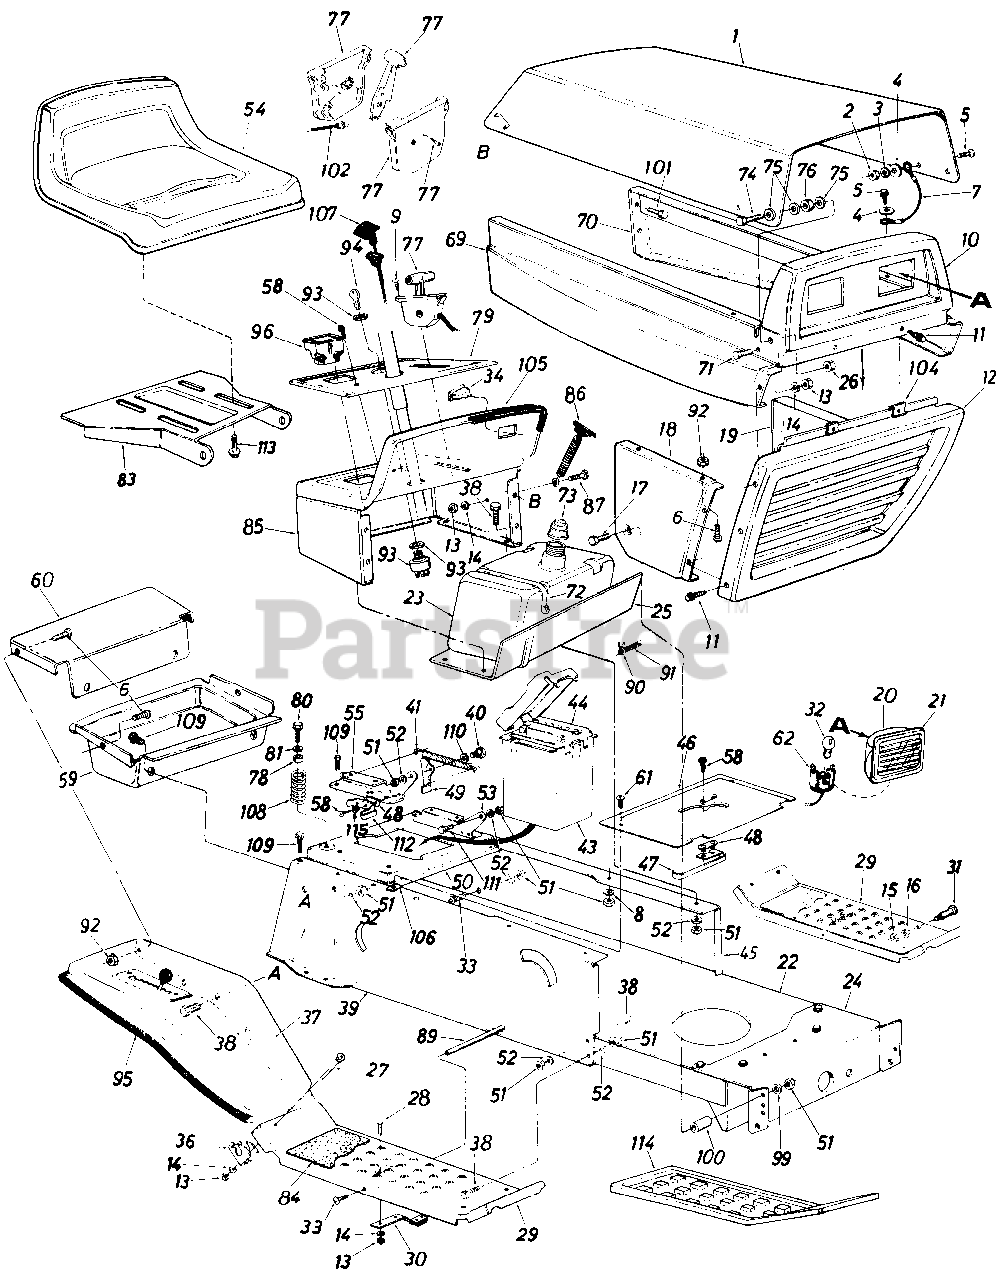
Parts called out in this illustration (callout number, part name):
3	L-Wash. #10 I.D.
4	Fl-Wash. .25" I.D. x .62"
5	Truss Scr. #10-24 x .375"
6	Truss Hd. Scr. #10-24 x .50"
7	Hood Stop
8	Ext. L-Wash. 5/16"
9	Truss Mach. AB-Tap Scr. #10 x .44
10	Front Grille Upper Ass'y.
11	Hex AB-Tap Scr. #10 x .50"
14	L-Wash. 1/4" I.D.
15	Hex Nut 3/8-16 Thd.
16	L-Wash. 3/8" I.D.
17	Hex Bolt 5/16-18 x 1.50"
18	R.H. Lower Side Panel
19	L.H. Lower Side Panel
20	Headlight Housing
21	Headlight Lens
22	Lower Frame
23	Fuel Tank
24	Front Pivot Brkt.
25	Fuel Tank Support
26	Hex Cent. L-Nut 3/8-16 Thd.
27	Carriage Bolt 1/4-20 x 2.00"
28	Carriage Bolt 1/4-20 x .62"
29	Running Board
30	Blade Brake Ass'y.
31	Shld. Bolt .50 Dia. x .84
32	Head Lamp
33	Truss Mach. Scr. 5/16-18 x .75" Lg.
34	Light Switch
36	Fender Clamp
37	Fender
39	R.H. Side Frame
40	Shld. Bolt .437" Dia. x .268"
41	Ext. Spring .75" O.D. x 5.31" Lg.
43	Battery Box w/Cover
44	12-V Battery
45	L.H. Side Frame
46	Shift Cover
47	Reverse Safety Switch
48	Insulator Nut Plate
49	Seat Lift Brkt.
50	Hitch Plate
51	Hex Nut 5/16-18 Thd.
52	L-Wash. 5/16" I.D.
53	Seat Pivot Brkt. Support-L.H.
54	Seat 8-7/8" High
55	Seat Pivot Brkt. Support-R.H.
58	Hex AB-Tap Scr. #8 x .50"
59	Tool Tray
62	Twist Lock-Lamp Socket
69	Side Panel-R.H.
70	Side Panel-L.H.
71	Hex Bolt 1/4-20 x .62" Lg.
72	Tie Strap
73	Fuel Cap Gauge
74	Hex Bolt 3/8-16 x 1.00" Lg.
75	Fl-Wash. .380" I.D. x 1.00"
76	Rubber Wash. .38" I.D. x .87" O.D.
77	Throttle Control Box Ass'y.
78	Bushing
79	Dash Panel Insert
80	Hex Wash. Hd. Tap Scr. 5/16-18 x 1" Lg.
81	Fl-Wash. .344" I.D. x .875" O.D.
83	Seat Pivot Bracket
84	Foot Pad
85	Dash Panel Ass'y.
86	Hood Latch Ass'y.
87	Hex Bolt 1/4-20 x .50" Lg.
89	Running Board Rod
90	Hose Clamp
91	Fuel Line
92	Hex Sems Nut #10-24 Thd.
93	Ignition Switch
94	Ignition Key
95	Trim Strip-57" Lg.
96	Ammeter
99	Belleville Wash. .34" I.D.
100	Spacer
101	Hex Wash. Hd. AB-Tap Scr. 1/4-20 x .62
102	Throttle Control Wire
104	Speed Nut #10Z
105	Trim Strip-15"
106	Speed Nut #10Z
107	Choke Control 29" Lg.
108	Compression Spring
109	Hex AB-Tap Scr. 5/16-18 x .75" Lg.
110	Spr-Wash. .445" I.D. x .75"
111	Shld. Bolt .437" Dia. x .162"
112	Spring Switch
113	Hex Hd. Tap Scr. 3/8-16 x .75" Lg.
114	Rubber Foot Pad L.H.
115	Fiber li'asher
